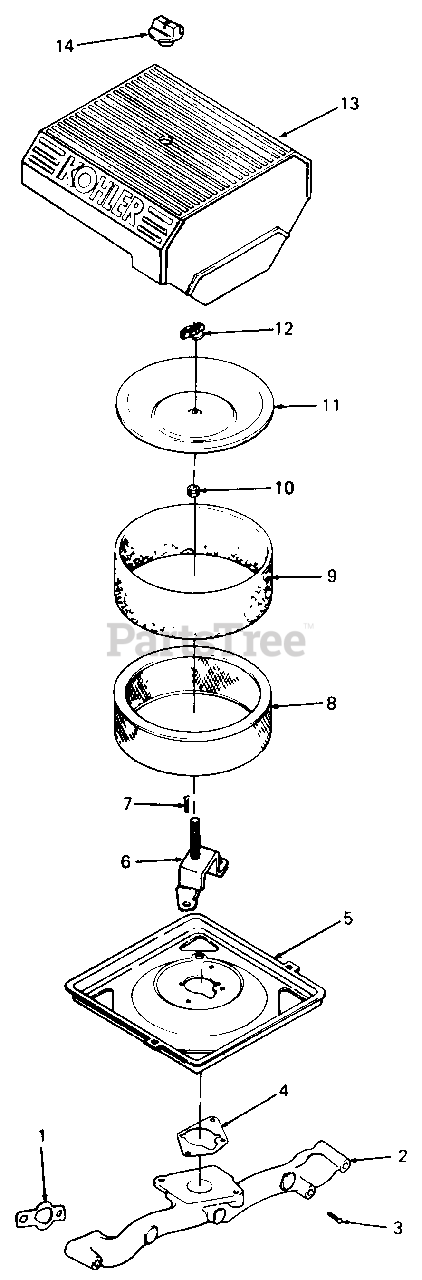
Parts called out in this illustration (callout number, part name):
1	Gasket, Intake Manifold
2	Manifold, Intake
3	Screw, M6 X 1.0 X 18
4	Gasket, Air Cleaner Base
5	Base, Air Cleaner
6	Bracket, Air Cleaner
7	Screw, M6 X 1.0 X 10
8	Element, Air Cleaner
9	Element, Pre-Cleaner
10	Seal, Air Intake
11	Cover, Inner Air Cleaner
13	Cover, Air Cleaner
14	Knob, Cover
